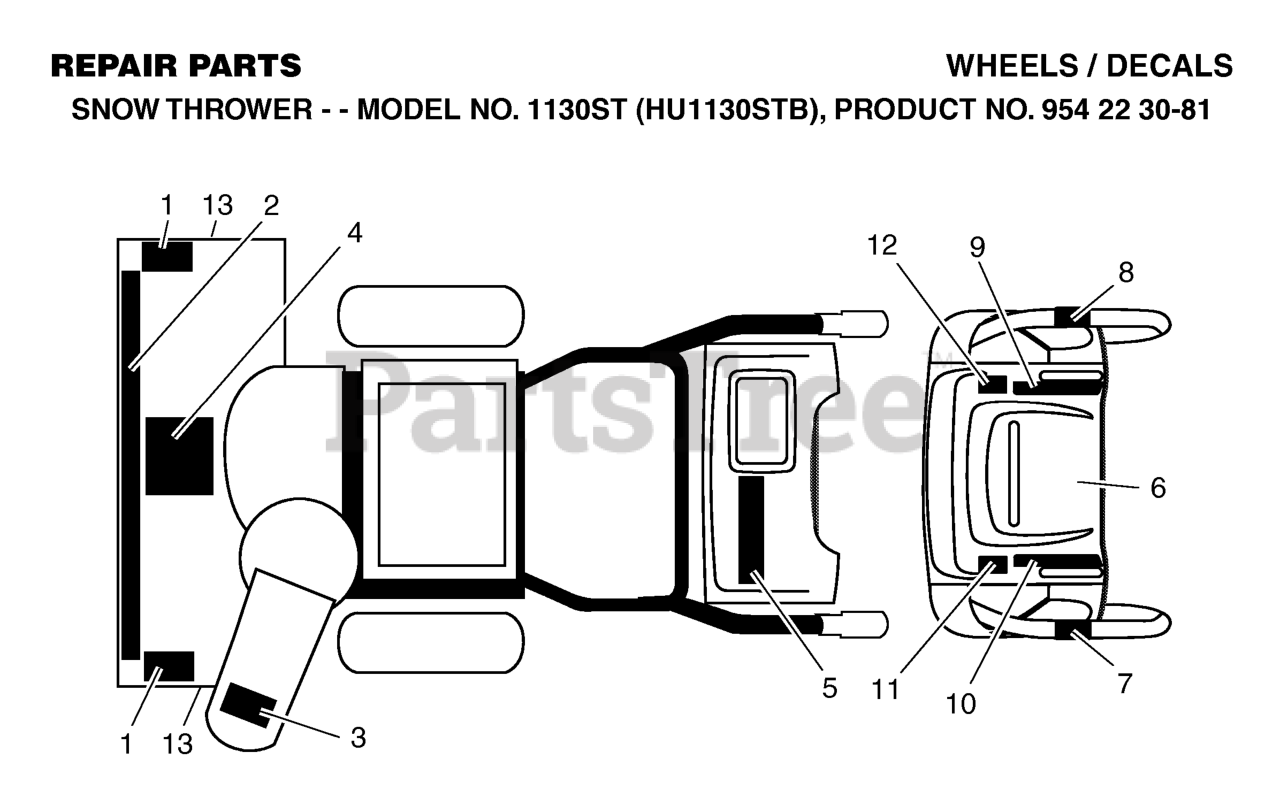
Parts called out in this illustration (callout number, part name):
1	DECAL DANGER
2	DECAL, HUSQVARNA
3	DECAL, DANGER DEFLECTOR
4	DECAL, DANGER
5	DECAL, HUSQVARNA 1130ST
6	DECAL.SNOWTHROWER.CONSOLE.INST
7	DECAL.TRACT.ASM.ENG.CLUTCH.K
8	DECAL, AUGER LEVER
9	DECAL, SPEED CONTROL
10	DECAL, REMOTE DEFLECTOR
11	DECAL, LH TRIGGER
12	DECAL, RH TRIGGER
13	DECAL, HUSQVARNA
